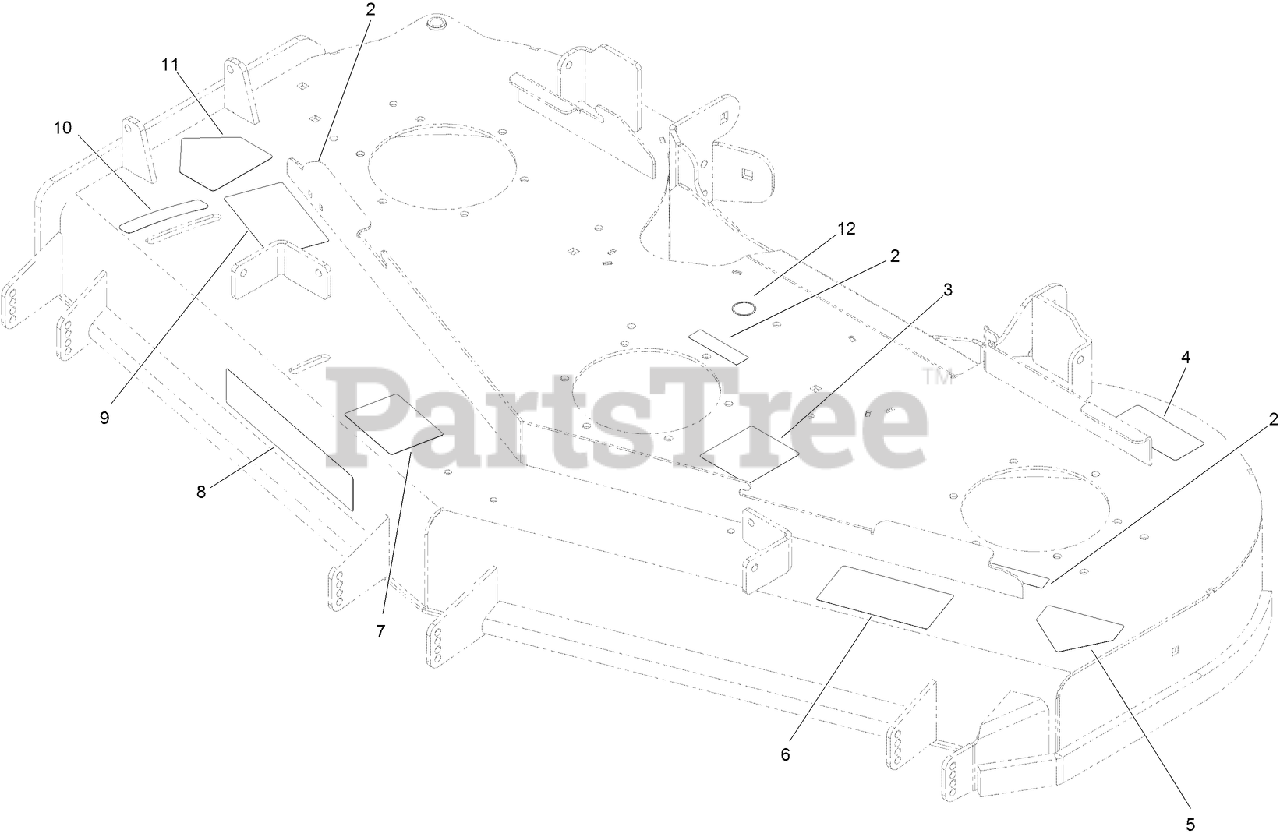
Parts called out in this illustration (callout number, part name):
2	DECAL-COVER, MISSING
3	DECAL-ROUTING, DECK BELT
4	DECAL-TORQUE
5	DECAL-DANGER
6	DECAL-DANGER, THROWN OBJECT
7	DECAL-SCALP, ANTI
9	DECAL-ADJUSTMENT, BAFFLE
10	DECAL-SETTING, BAFFLE
11	DECAL-DANGER
12	DECAL-GREASE
